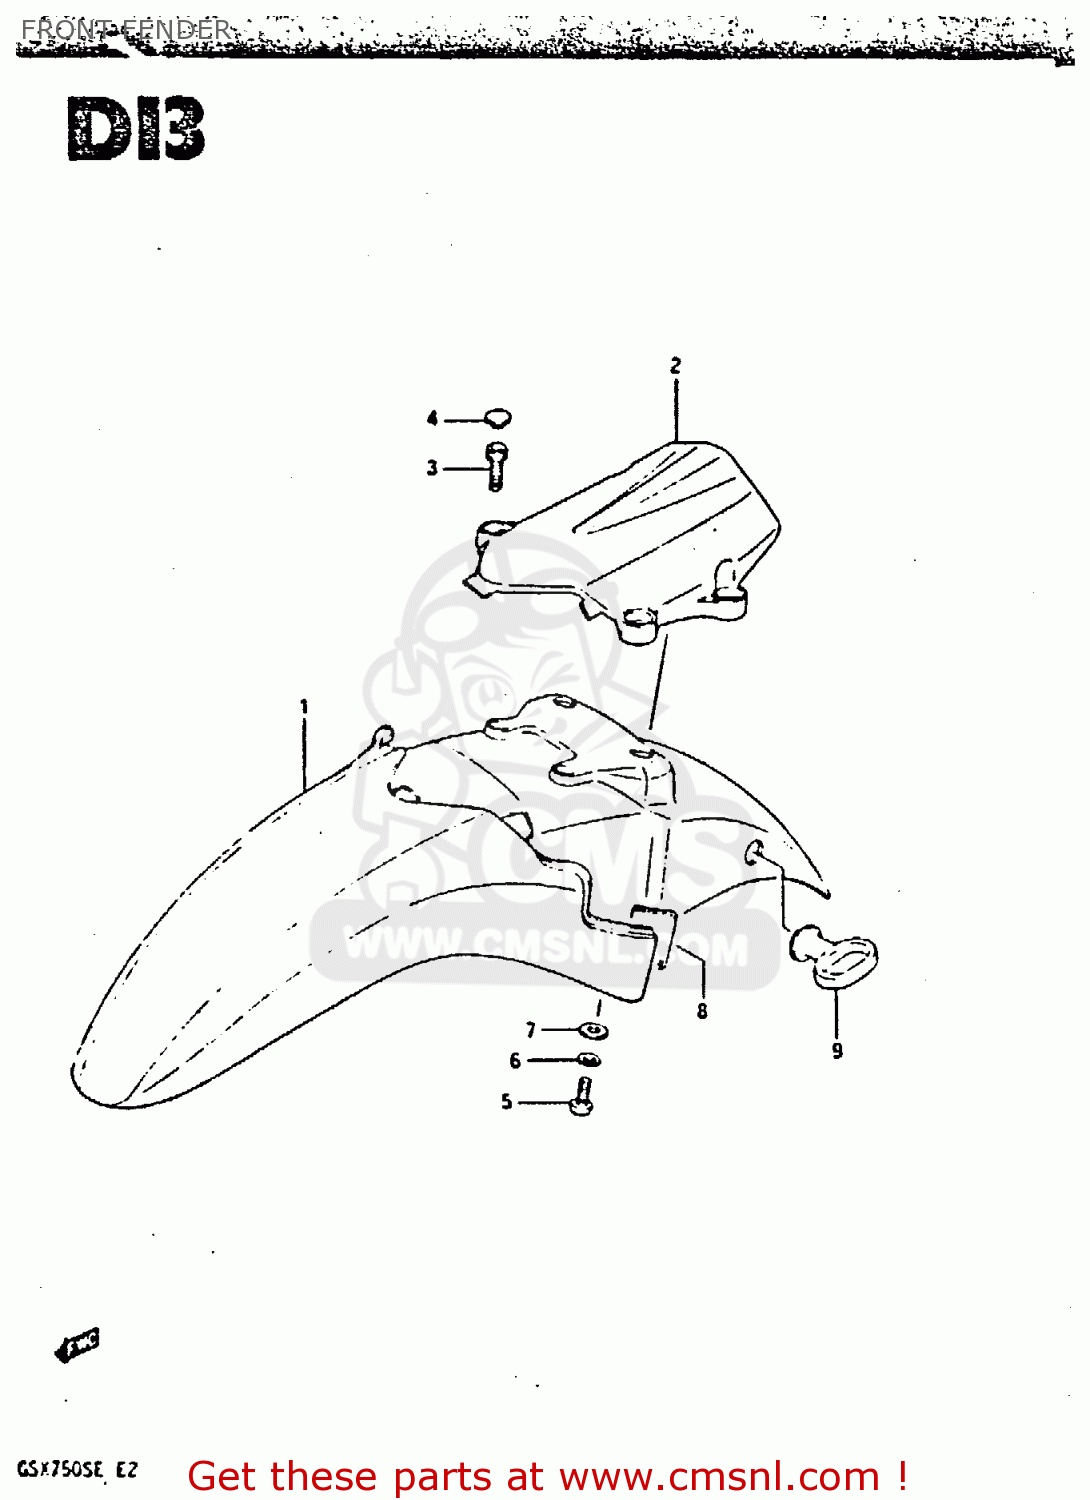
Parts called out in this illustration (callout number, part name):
1	FENDER, FRONT (WHITE)
2	BRACE, FRONT FENDER (GOLD)
3	BOLT
4	CAP(OD:14.5)
5	SCREW 6X12
6	WASHER,LOCK
7	WASHER
8	CUSHION
9	GUIDE,CABLE
